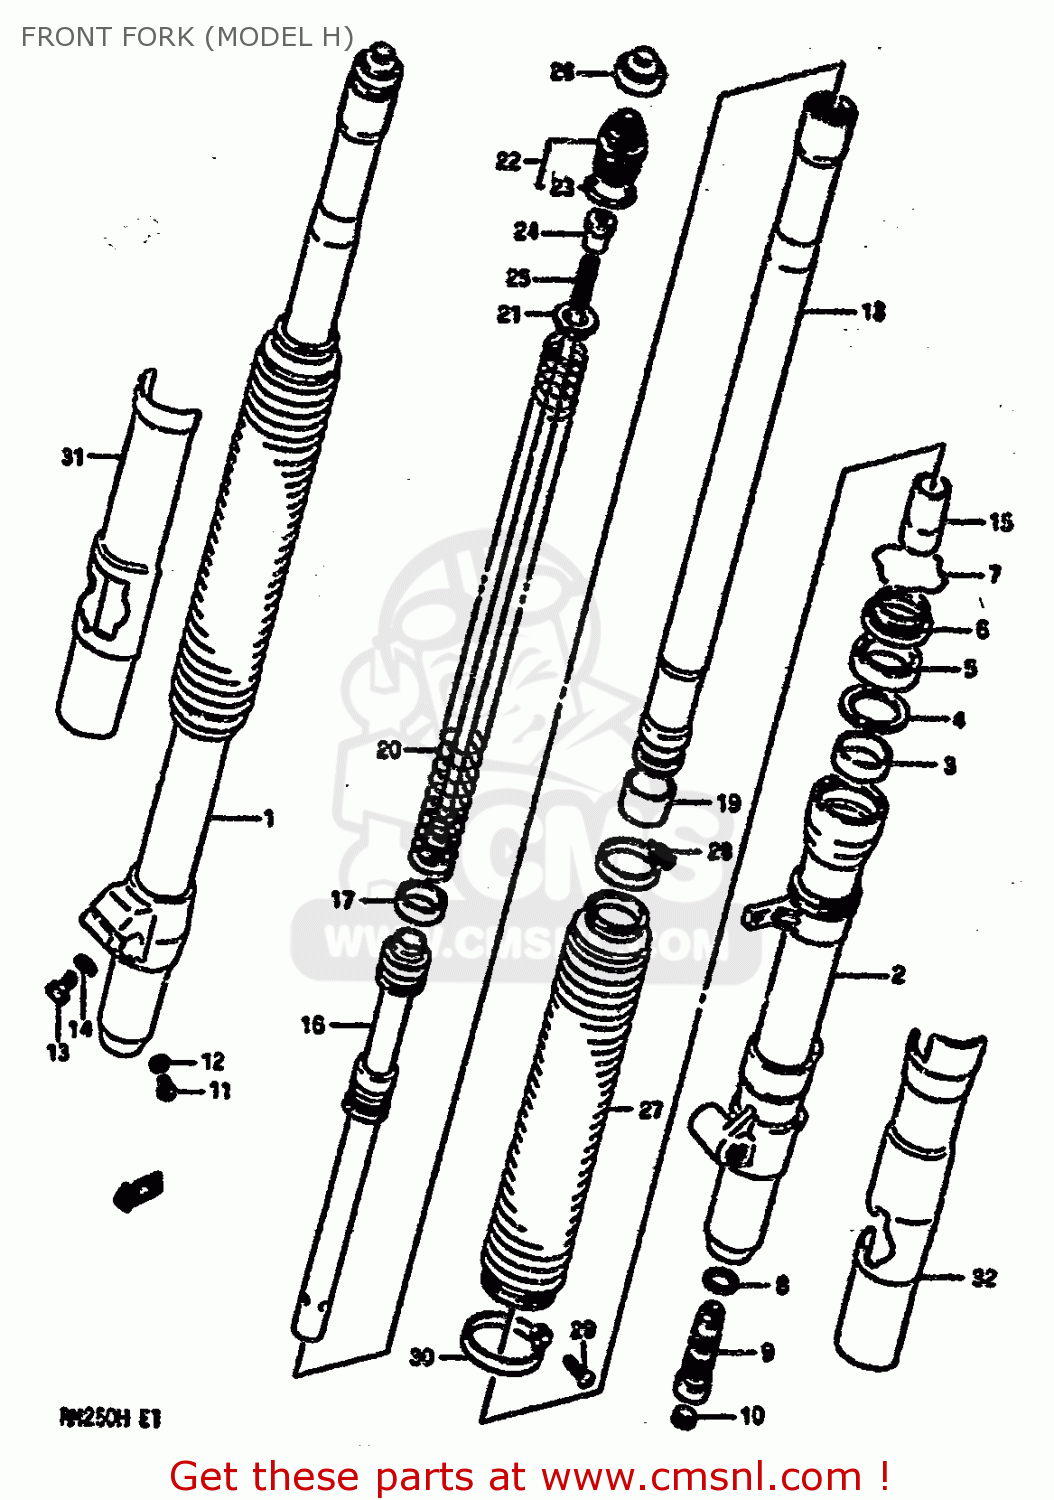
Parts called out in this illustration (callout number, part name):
1	OUTER TUBE,RH
2	TUBE,OUTER,LEFT
3	METAL,SLIDE
4	WASHER
5	OIL SEAL,FRONT FORK
6	SEAL,DUST
7	RING,STOPPER
8	GASKET
9	VALVE
10	CAP,FRONT FORK DF
11	SCREW 4X6
12	GASKET,DRAIN,PLUG (NAS)
13	BOLT
14	WASHER,LOCK
15	PIECE,OIL LOCK
16	CYLINDER,FRONT FORK
17	RING,FRONT FORK PISTON
18	TUBE,FORK,INNER
19	PISTON
20	SPRING,FRONT FORK
21	GUIDE,FRONT FORK SPRING
22	CAP
23	O RING
24	NUT
25	ROD,PISTON
26	CAP
27	BOOT
28	BAND,BOOT,UPPER
29	SCREW,BAND BOOT(3.5X10)
30	BAND,BOOT LWR
31	PROTECTOR,RIGHT
32	PROTECTOR,LEFT
